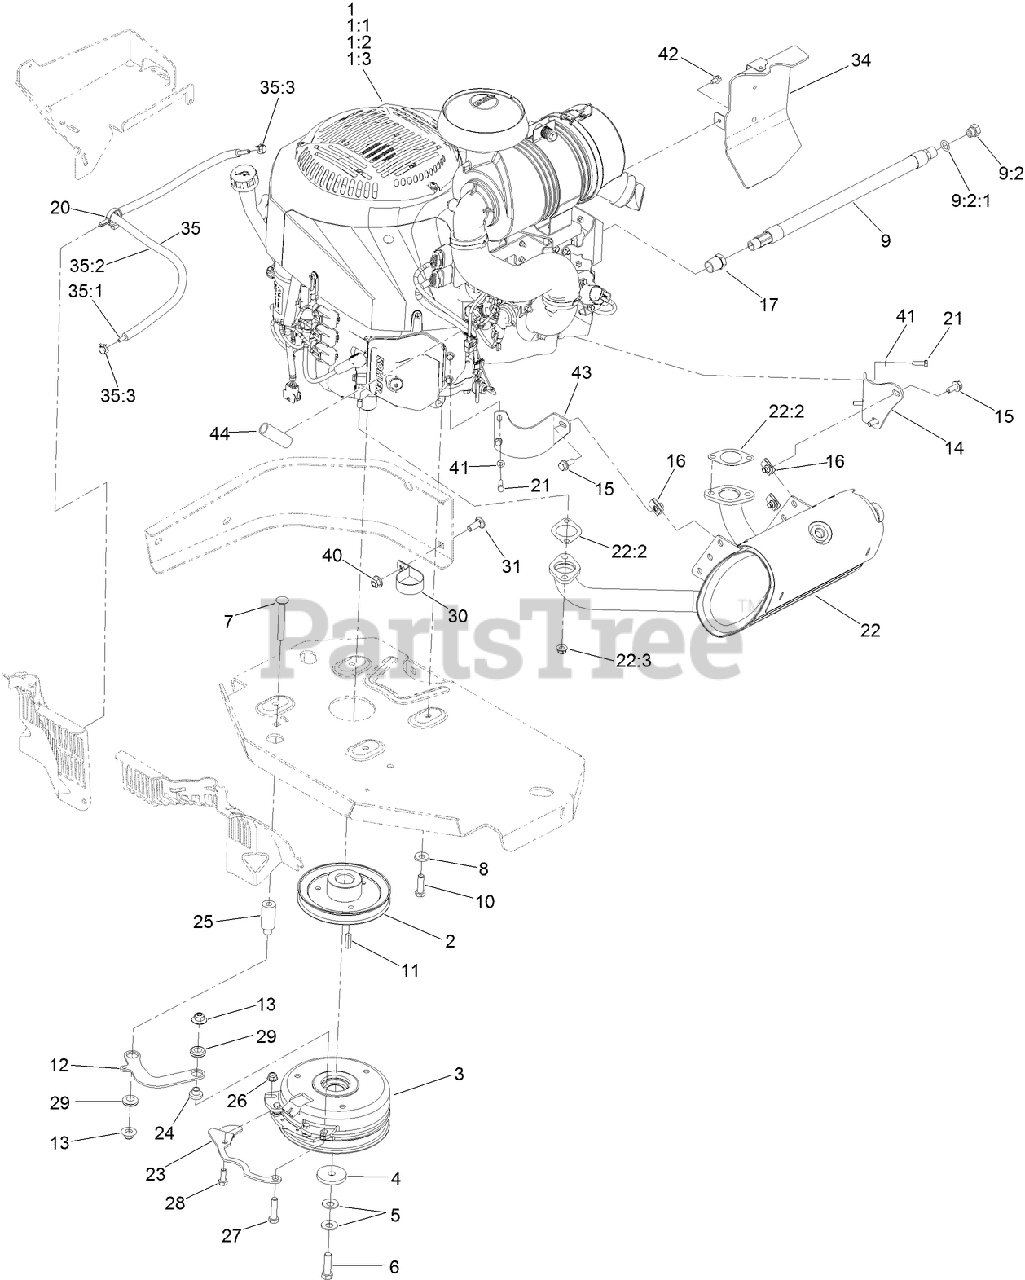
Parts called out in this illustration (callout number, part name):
1:1	KOHLER 52 050 02-S ENGINE OIL FILTER
1:2	KOHLER 25 083 01-S ENGINE AIR FILTER
1:3	KOHLER 25 083 04-S SAFETY FILTER
2	SHEAVE
3	CLUTCH KIT
4	WASHER-CLUTCH
5	WASHER-SPRING
6	SCREW-HH, W/LOCTITE
7	SCREW-CARR
8	WASHER-BELLEVILLE
9	OIL DRAIN HOSE ASM
9:2	PLUG-HH
9:2:1	O-RING
10	SCREW-HH
12	LINK-ANCHOR, CLUTCH
13	NUT-FLANGE, NI
14	BRACKET-MUFFLER
15	SCREW-HHF
16	NUT-U
17	BUSHING
20	CLAMP-HOSE
21	SCREW-HH
22	MUFFLER KIT
22:2	GASKET-EXHAUST
22:3	NUT-FLANGE, LOCK
23	BELT-GUIDE
24	SPACER
25	SPACER
26	NUT-HF, NI
27	SCREW-HH
28	SCREW-HH
29	GROMMET-RUBBER
30	CLAMP-R
31	SCREW-CARR
34	REAR BAFFLE ASM
35	FUEL LINE ASM
35:1	HOSE-FUEL
35:2	SLEEVE, THERMAL
35:3	CLAMP-HOSE
40	NUT-HF, NI
41	WASHER-SPRING
42	SCREW-HWH
43	BRACKET-MUFFLER, FRONT
44	CONDUIT-CONVOLUTED
